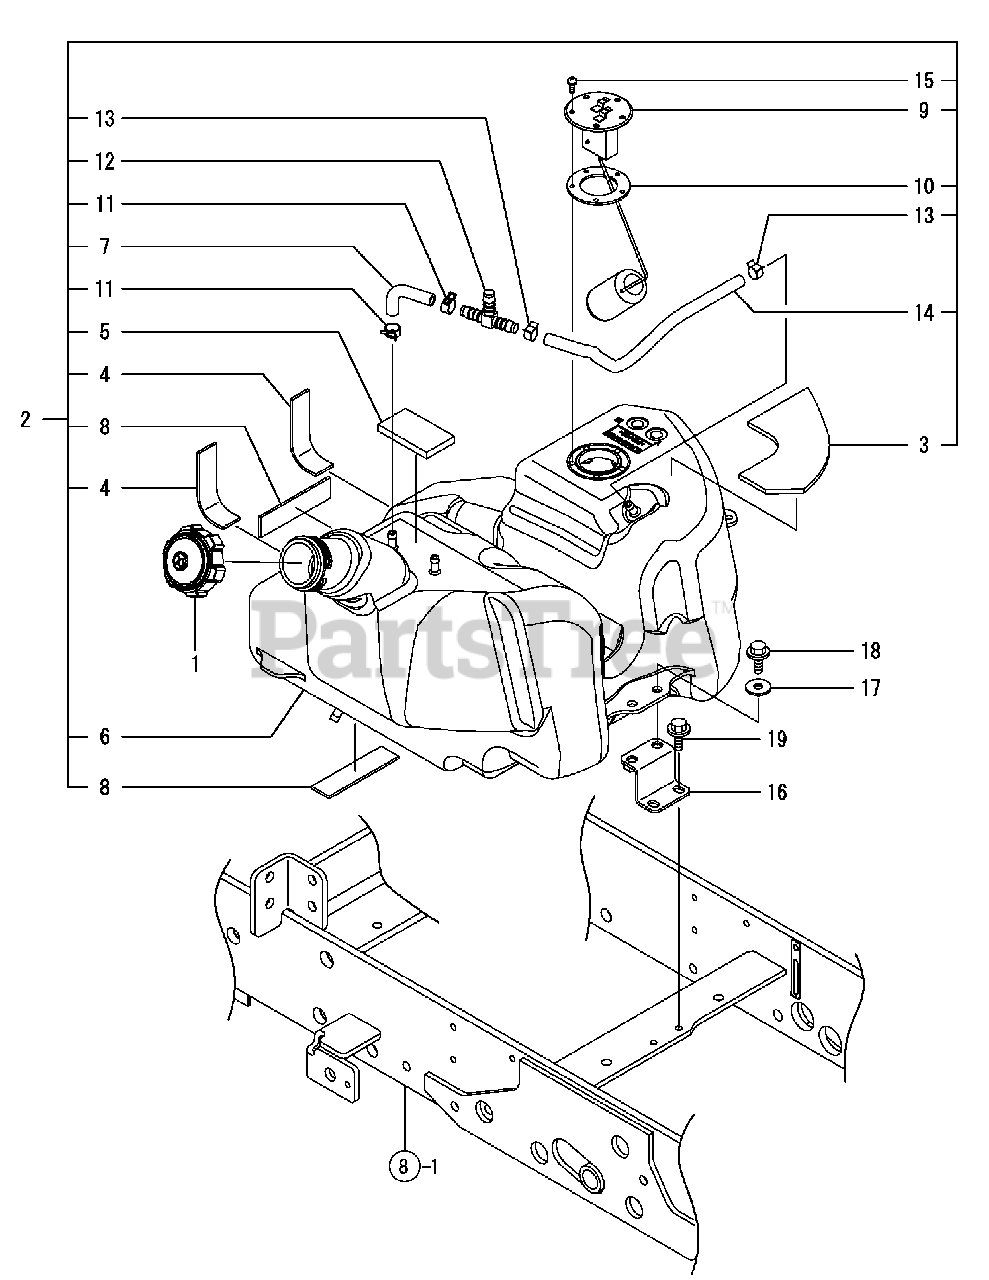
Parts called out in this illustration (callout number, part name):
1	CAP, FUEL TANK
2	TANK ASSY, FUEL
3	CUSHION,FUEL TANK RH
4	CUSHION,FUEL TANK SI
5	CUSHION,FUEL TANK
8	RUBBER, 100X25X3
9	SENDER ASSY, FUEL
10	GASKET, FUEL GAUGE
14	HOSE, 7.3 X 260
18	BOLT M 8X 16 PLATED
19	BOLT M 8X 16 PLATED
